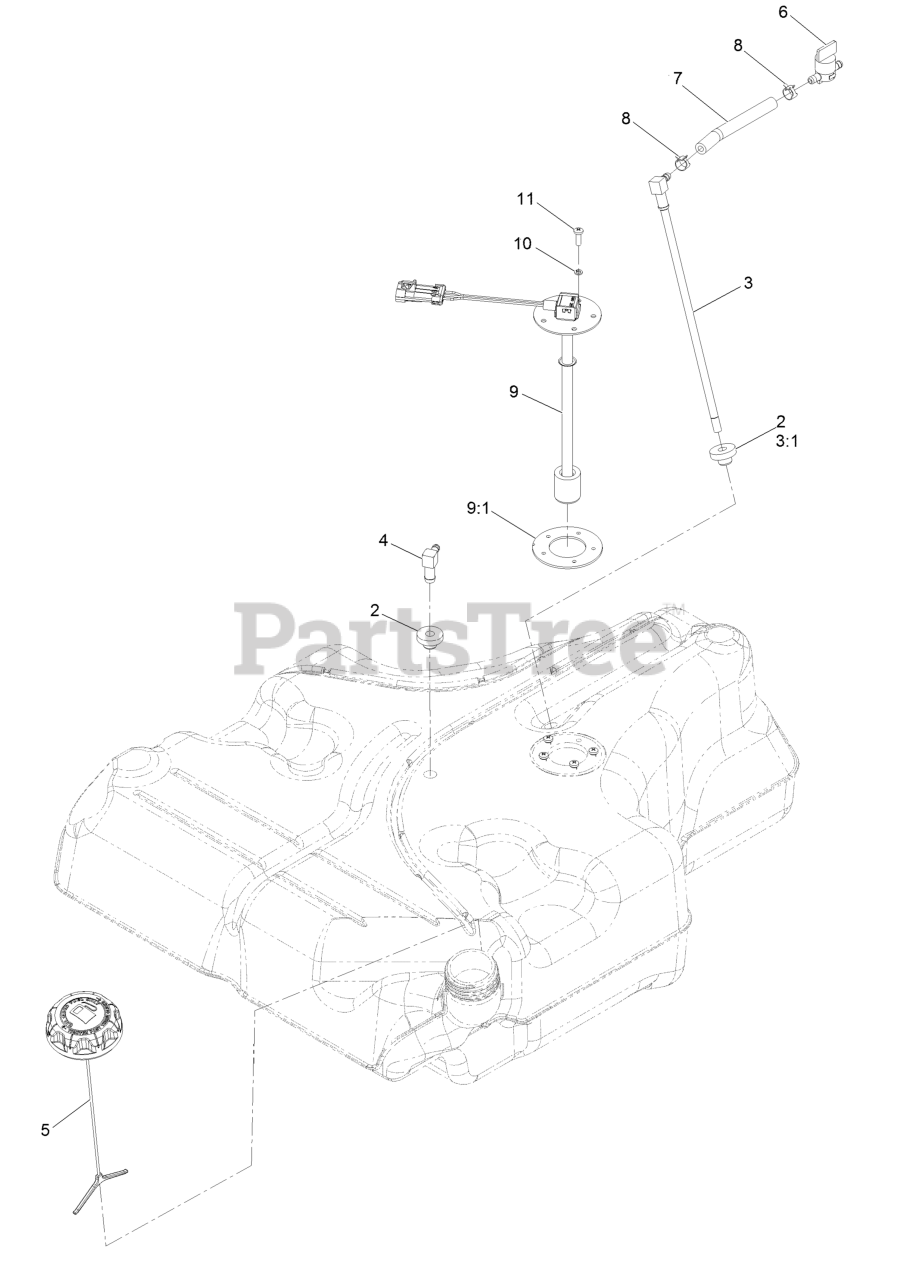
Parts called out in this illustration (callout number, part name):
2	BUSHING
3	FUEL LINE KIT (WITH GROMMET)
3:1	BUSHING
4	FITTING-90 ELBOW
5	CAP-FUEL, RATCHETING
6	VALVE-FUEL
7	HOSE-FUEL
8	CLAMP-HOSE
9	SENDER-LEVEL, FUEL (W/GAS
9:1	Gasket-Sender
10	WASHER-LOCK
11	SCREW-PPH
